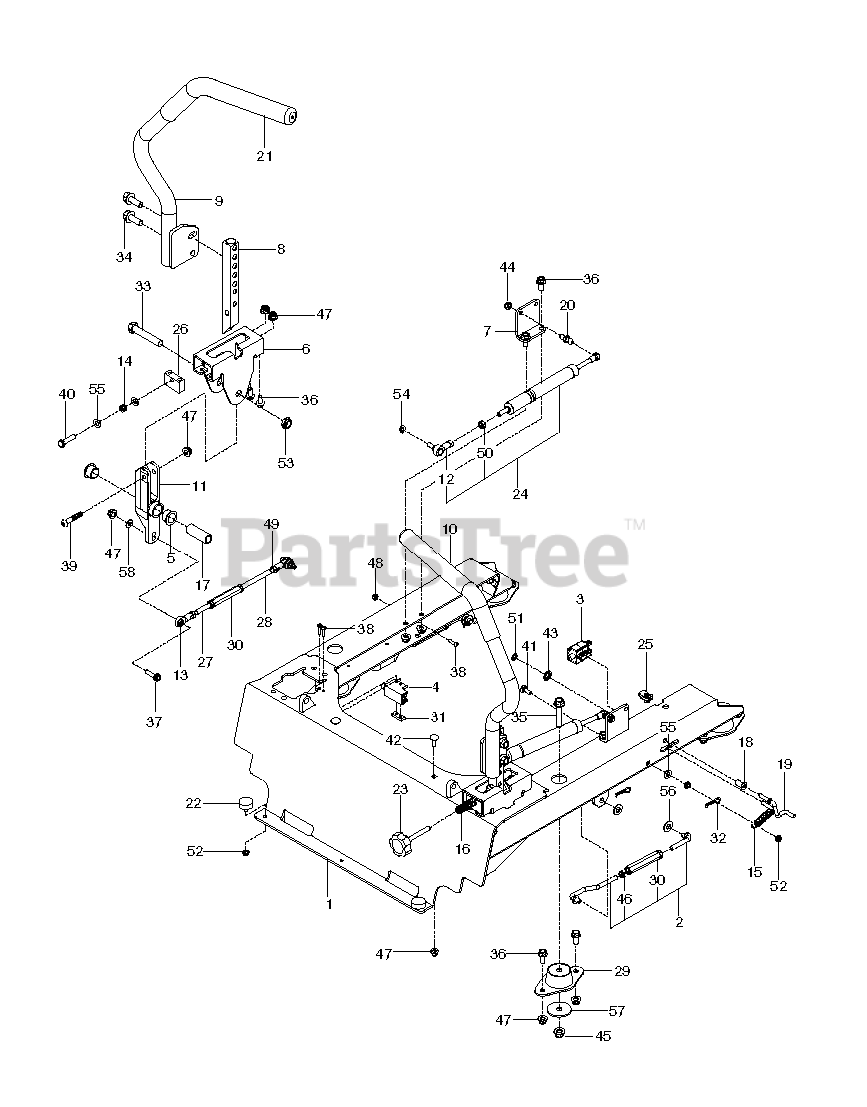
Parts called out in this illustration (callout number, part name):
1	FRAME SEAT MOUNT ORANGE
2	ASSEMBLY, SEAT STRUT
3	SWITCH, BRAKE 3P
4	SWITCH INTERLOCKT
5	BEARING, FLANGE
6	BRACKET, CONTROL
7	BRACKET.DAMPNER
8	LEVER, MOTION
9	LEVER.WITH GRIP.RT
10	LEVER.WITH GRIP.LT
11	LEVER.CONTROL.SHORT
13	BALL JOINT, RIGHT HANDED
15	SPRING, EXTENSION
16	SPRING COMPRESSION 2.0
17	SPACER, PIVOT CONTROL
18	BUSHING, 1/4 FLANGE
19	LINK, SWITCH
20	STUD.BALL.10MM
21	GRIP - DRIVE LEVER 12"
22	BUMPER, 1/4-20 STUD, 1/4
23	KNOB
24	ASSEMBLY, DAMPENER
25	U-CLIP 5/16-18 NUT RETAINER
26	BLOCK.TRACKING
27	LINKAGE, CONTROL, FT
28	LINKAGE, CONTROL, RR
29	MOUNT, ISO
30	TURNBUCKLE, 3/8
31	TAPPED PLATE
32	HAIRPIN #2
33	HCS 1/2C X 2 3/4
34	HHFS 3/8-16 X 1 GRD 5 ZD
35	HHFS 3/8-16 X 2.0 GD 5
36	HHFS 5/16-18 X 3/4
37	RHSNB 1/4C X 3/4
38	SCR #10-24 X .75 SKT HD BLK
39	SCREW 5/16-18 X 1 3/4 BTN-HD
40	HCS 5/16C X 1 1/4
41	RHSNB 1/4C X 3/4
42	BOLT 5/16C X 3/4" CARRIAGE
43	NUT 3/8 PALNUT RTNG BLK PHOS
44	NUT 5/16 NYLOC
45	NUT 3/8-16 HEX FLG NYLOC ZD
46	NUT 3/8-24 JAM
47	5/16-18 NYLOC FLANGE NUT
48	NUT 10-24 NYLOC
50	NUT M8 X 1.25 STD HEX
51	NUT PUSH
52	JAM NUT 1/4C (2 2 PW01)
53	NUT 1/2-13 HEX JM NYL
54	WASHER.LOCK.HVY.HLCL.SPR.5/16
55	FLAT WASHER 5/16 SAE
56	WASHER 3/8 SAE FLAT
57	WASHER, 3/8 SPEC
58	WASHER 5/16 FLAT
